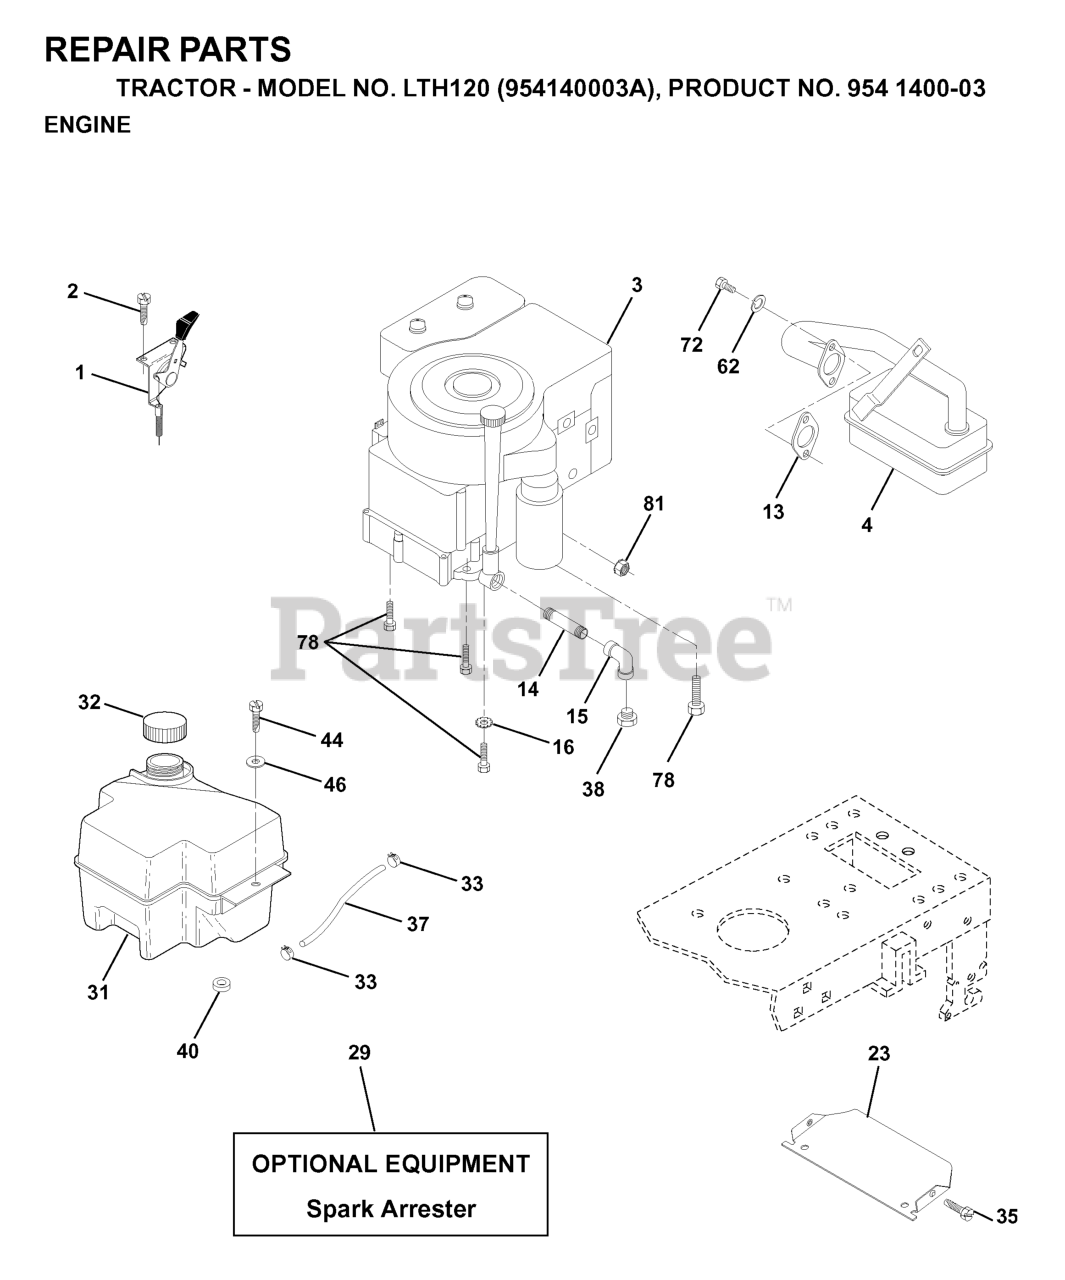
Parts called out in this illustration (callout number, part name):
1	CHOKE CONTROL
2	SCREW LT
4	MUFFLER.SINGLE.B&S.10-12HP
13	GASKET.ENG.1.313 ID.TIN PLATED
14	Nipple Pipe 3/8 Npt X 3-1/2
15	ELBOW
16	LOCKWASHER
23	SHIELD HEAT
29	KIT.SPARK ARRESTOR 794945 B&S
31	FUEL TANK
32	FUEL CAP
33	HOSE CLAMP
35	SCREW.THDROL.5/16-18X3/4.TTY
37	LINE.FUEL.20
40	BUSHING.SNAP.NYL.BLK.
44	SCREW HEX CRT
46	WASHER
62	WASHER.LOCK.HVY.HLCL.SPR.5/16
72	SCREW
78	SCREW
81	NUT FLANGE 1/4-20 STARTER NUT
